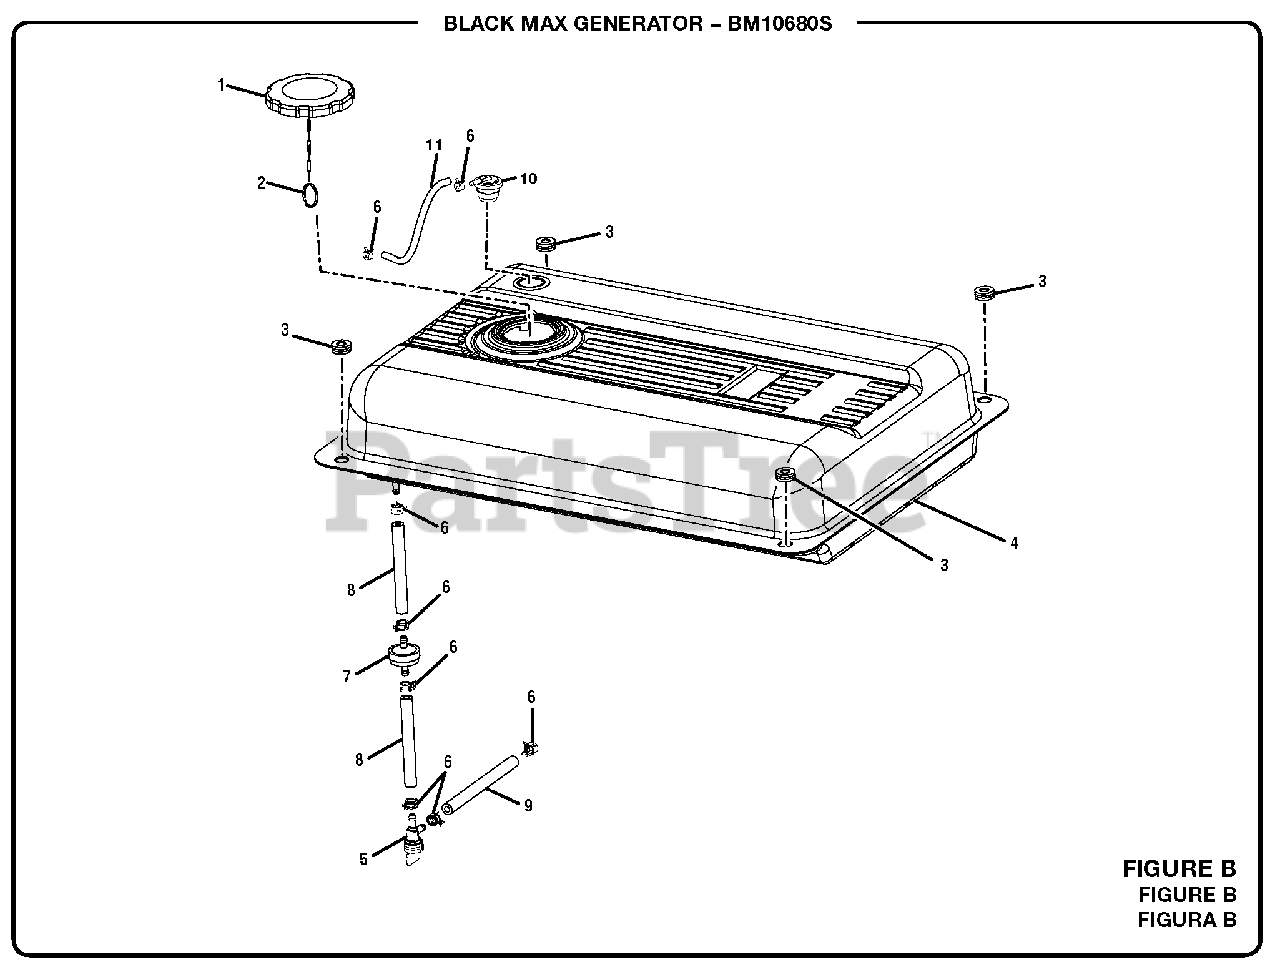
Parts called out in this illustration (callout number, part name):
1	Fuel Tank Cap
2	Ring Clip
3	Bushing w/Insert
4	Fuel Tank
5	Fuel Valve
6	Fuel Line Clamp (1/2 in.)
7	Fuel Line Filter
8	Fuel Line (1/4 in.)
9	Fuel Hose (5 mm)
10	Vapor Vent
11	Vapor Hose
